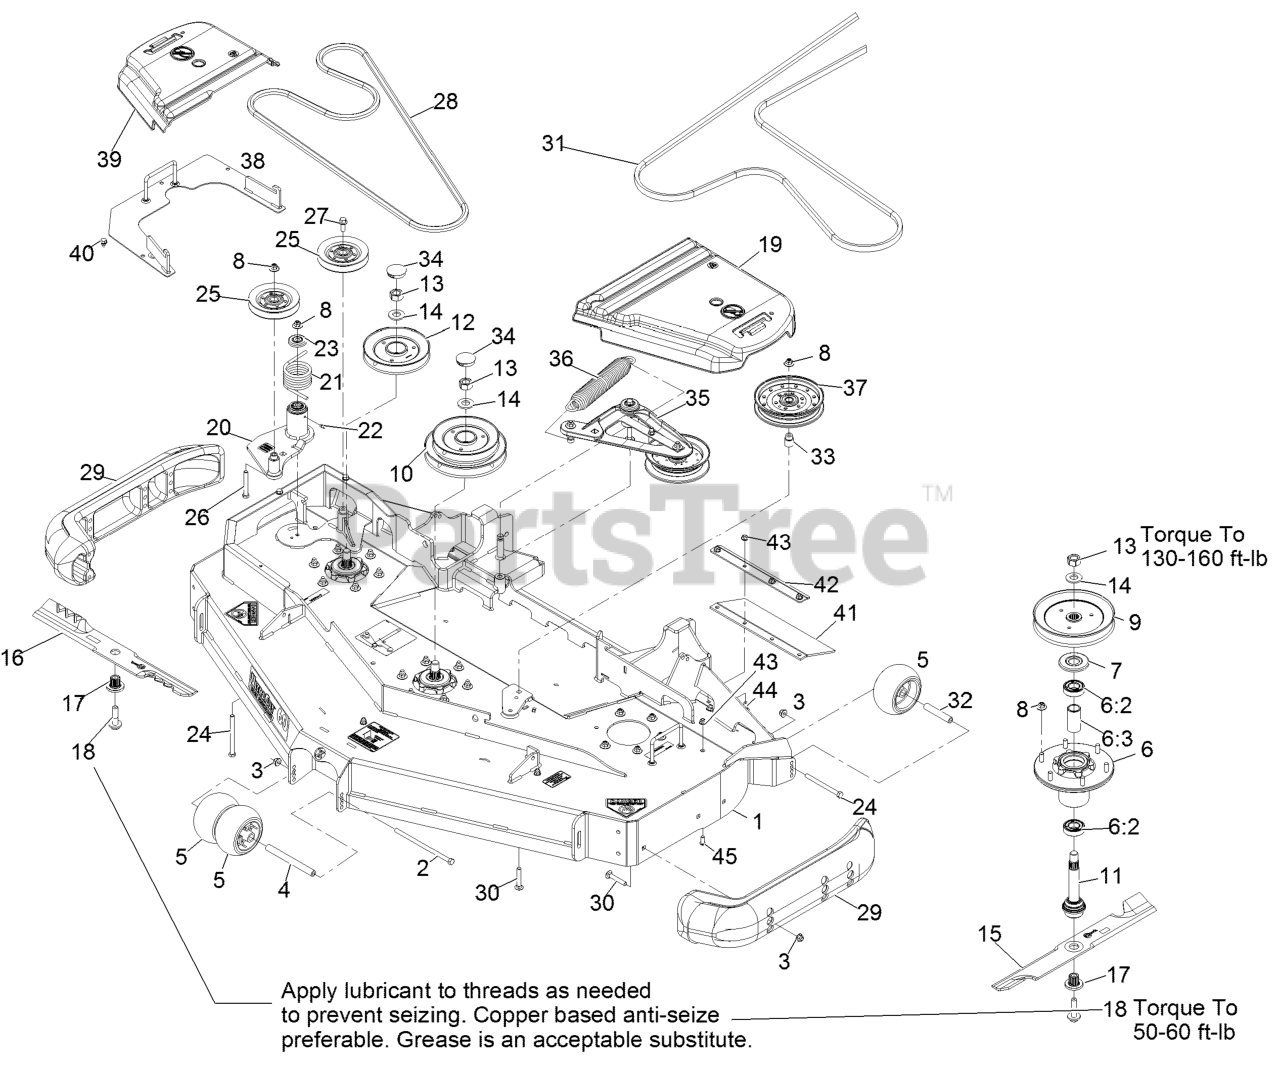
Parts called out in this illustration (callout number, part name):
1	DECK-RD60 NLZ, W/DECALS
2	SCREW-HH
3	NUT-HF, NI
4	SPACER-WHEEL
5	ROLLER-SCALP, ANTI
6	ASM-CUTTER HSG WITH BEARINGS
6:2	BEARING-BALL
6:3	SPACER-BEARING
7	GUARD,BEARING TOP .989
8	Nut-Nyloc 3/8-16 Flg
9	SHEAVE,BLADE DRIVE 7.25
10	SHEAVE, DOUBLE 60RD
11	ASM-SPINDLE AND SEAL
12	SHEAVE-RD REV DRIVE SERIE
13	NUT-HEX
15	Blade-Extreme 2, 20.50"
16	Blade-Low Lift 20.5, Rd60
16	Blade-Extreme 2-20.50, Rd60
17	BUSHING,SPLINED
18	SCREW,SEMS 1/2-20 X 2.19
19	COVER-BELT, LH
20	IDLER ASM
21	SPRING-TORSION
22	FITTING-GREASE
23	GUARD-TOP
24	SCREW-HH
26	SCREW-HH
27	SCREW-HHF
28	BELT
29	SKID-BUMPER, DECK
30	Bolt-Carriage 3/8-16 X 2 1/4
31	BELT
32	TUBE-SPANNER
33	BUSHING-IDLER
34	PLUG,BLACK NYLON 1.75
35	DECK IDLER ASM
36	SPRING-EXTENSION
38	COVER-DRIVE REVERSE
39	COVER-BELT, RH
41	GUARD-TIRE
42	SUPPORT-OUTER FLAP
43	NUT-HF, NI
44	SCREW-CARR
45	SCREW-HSBH
